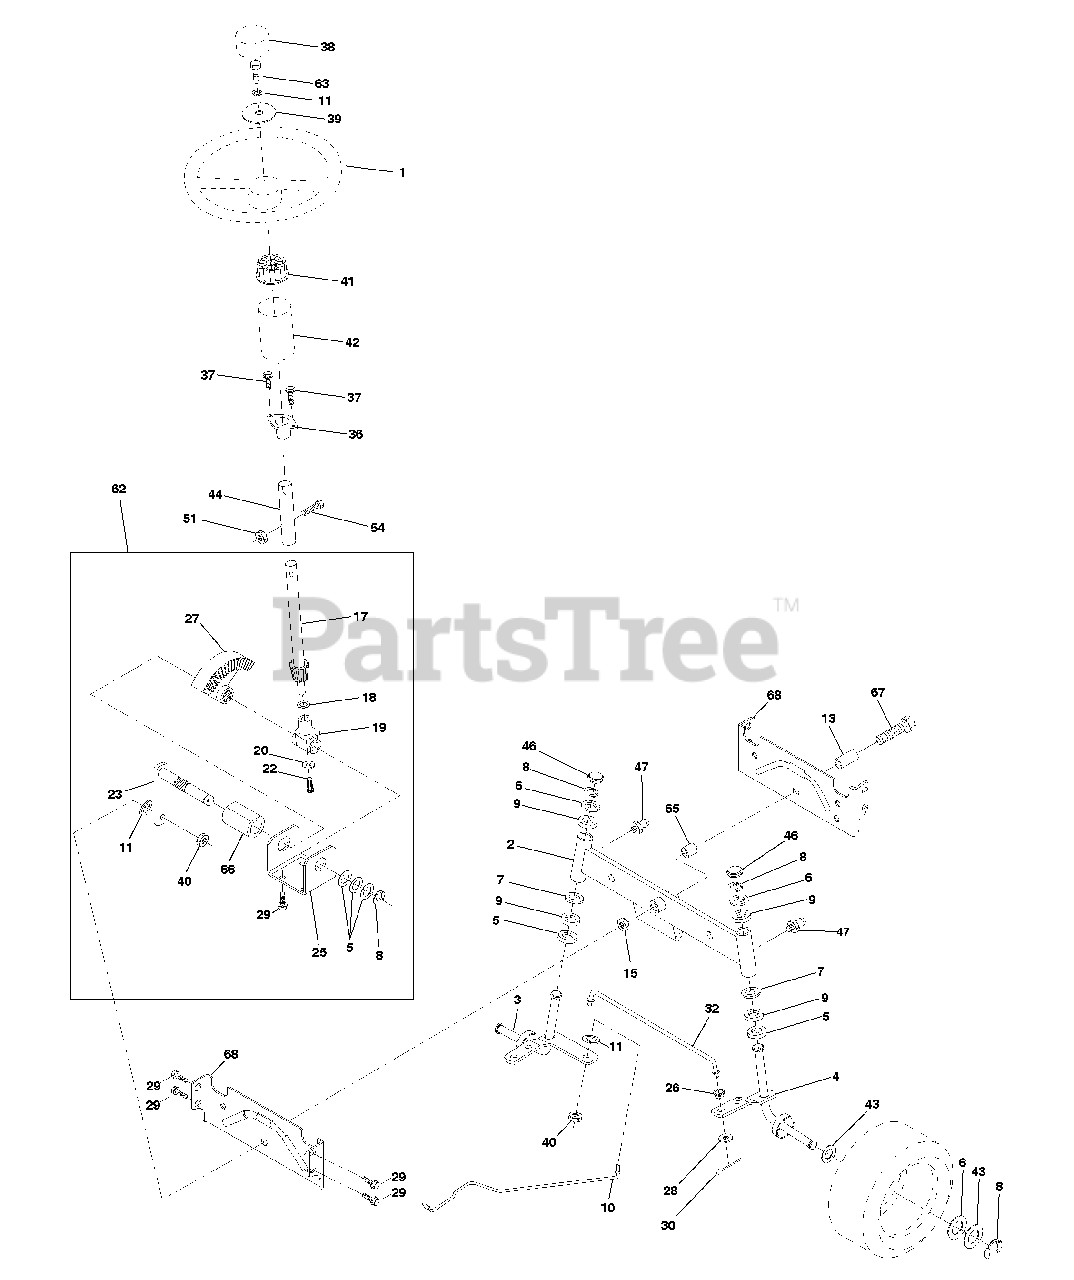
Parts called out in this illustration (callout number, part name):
1	Wheel Steering
2	Axle Asm STMP Dropped STL
3	Spindle Asm LH
4	Spindle Asm RH
5	Bearing Race Thrust Harden
6	Washer 25/32 X 1-5/8 X 16 Ga
7	Washer 27/32 X 1-1/4 X 16 Ga
8	Ring Klip #t5304-75
9	Bearing Col Strg Blk
10	Link Drag Extended Stamp
11	Washer Lock Hvy Hlcl Spr 3/8
13	Bearing Axle STLT/GT
15	Nut Lock Flange 5/8-11 Unc
17	Shaft Asm Strg
18	Washer Thrust 515 x 750 x 033
19	Support Shaft
20	Washer Shim 1/4 X 5/8 X 062
22	Screw Hex Socket 1/4-20 x 5/8
23	Shaft Asm Pittman
25	Bracket Steering
26	Bushing Link Drag Blk LR
27	Gear Sector
28	Washer 13/32 X 7/8 X 16 Ga
29	Screw Thdrol 3/8-16 x 3/4 Ty-tt
30	Pin Cotter 1/8 X 3/4 Cad
32	Rod Tie Wire Form 19 75 Mech
36	Bushing Strg
38	Insert Cap Strg Wh Au
39	Washer 13/32 X 2-3/8 X 8 Ga
40	Lock nut
41	Adaptor Wheel Strg
42	Boot Steering Shaft
43	Washer 25/32 X 1 1/4 X 16 Ga
44	Extension Steering Shaft LR/LT
46	Cap Spindle Fr Top Blk
47	Fitting Grease
51	Nut Lock Hex w/Ins 5/16-18
54	Bolt Fin Hex 5/16-18 Unc x 1-1/4
62	Kit, Steering Assembly Svc
63	Bolt Fin Hex 3/8-16unc x 1 Gr. 5
65	Spacer Axle
66	Bearing Arm Pittman
67	Bolt, Fin Hex 5/8-11 UNC x 2-3/4
68	Axle, Brace
